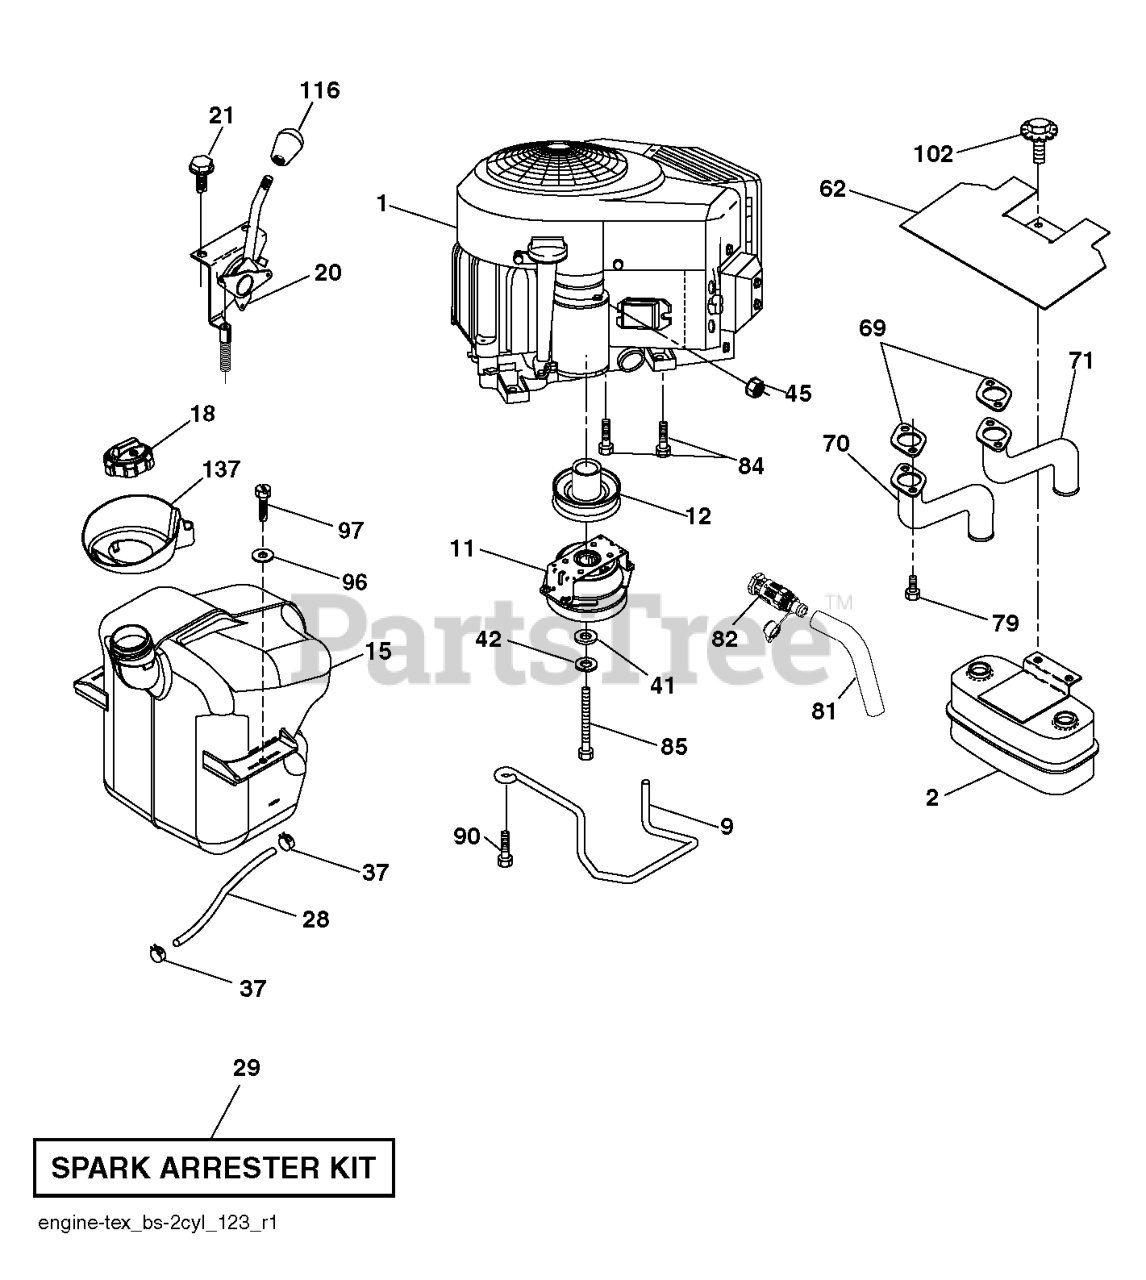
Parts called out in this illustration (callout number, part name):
2	MUFFLER.ASM.TWN.EXTNDED.DFLCTR
9	KEEPER BELT ENGINE
11	CLUTCH.ELECTRIC.LT.48"*
12	PULLEY.ENGINE.TUFFTORQ
15	FUEL TANK TANK. ASSEMBLY. EXTE
18	CAP.ASM.FUEL.2.25"TOP.TURN
20	CONTROL THROTTLE/CHOKE
21	SCREW.#10 X 0.750.BOS
28	LINE.FUEL.20
29	KIT.SPARK ARRESTOR 794945 B&S
37	HOSE CLAMP
42	LOCKWASHER
45	NUT
62	SHIELD.HEAT.MUFFLER
69	GASKET.MUFFLER
70	EXHAUST.TUBE.LH.BS/TWIN
71	EXHAUST.TUBE.RH.B&S.TWIN.INTEK
79	SCREW.SOCKET.HEAD.5/16-18
81	TUBE, DRAIN OIL ASM.
82	VALUE.OIL.DRAIN
84	SCREW.3/8-16
85	BOLT HEX 7/16-20X4-1/4"
87	BOLT.5/16-18UNCX3/4 W/SEMS.BLK
90	SCREW 3/8-16X1
96	WASHER
97	SCREW HEXWSHR 1/4-20X3/4
116	KNOB - SHIFT
